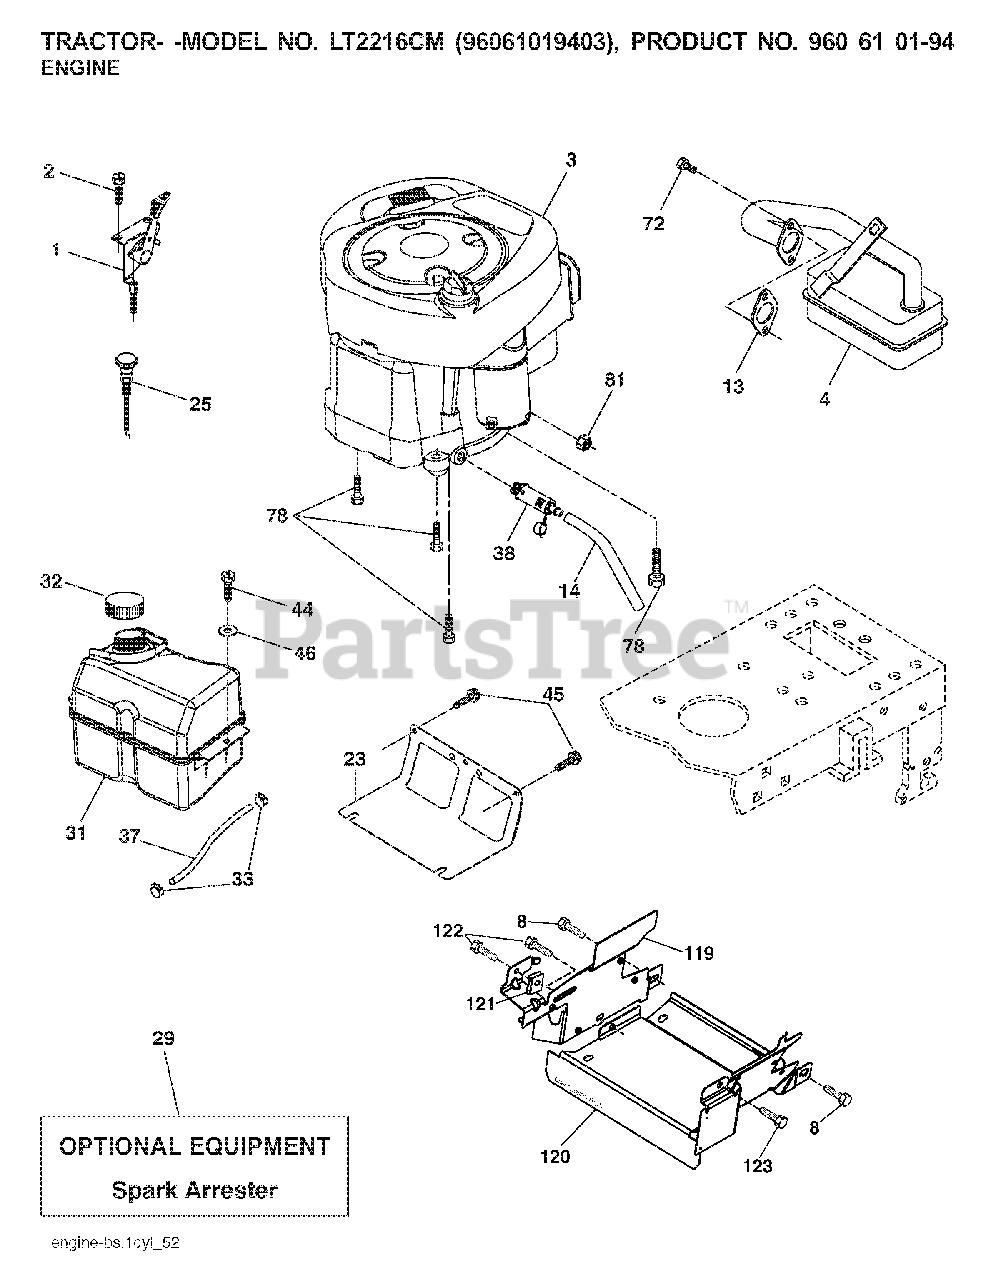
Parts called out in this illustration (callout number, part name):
1	CONTROL TH/CH FLAG
2	SCREW
8	BOLT, 5/16-18 X 1 3/4
13	REPL BY 532 27 22-93
14	TUBE, DRAIN OIL ASM.
23	SHEILD.BROWNING.DBR.GUARD
29	ARRESTER SPARK (OPTIONAL)
31	TANK FUEL
32	FUEL CAP
33	HOSE CLAMP
37	LINE.FUEL.20
38	PLUG DRAIN OIL EASY
44	SCREW HEXWSHR 1/4-20X3/4
45	SCREW, 3/8-16X3/4
46	WASHER
72	SCREW.SOCKET HD.5/16-1
78	SCREW.3/8-16
81	NUT
102	SCREW
122	SCREW.1/4-20X5/8
123	SCREW, 5/16-18 X 1/2
